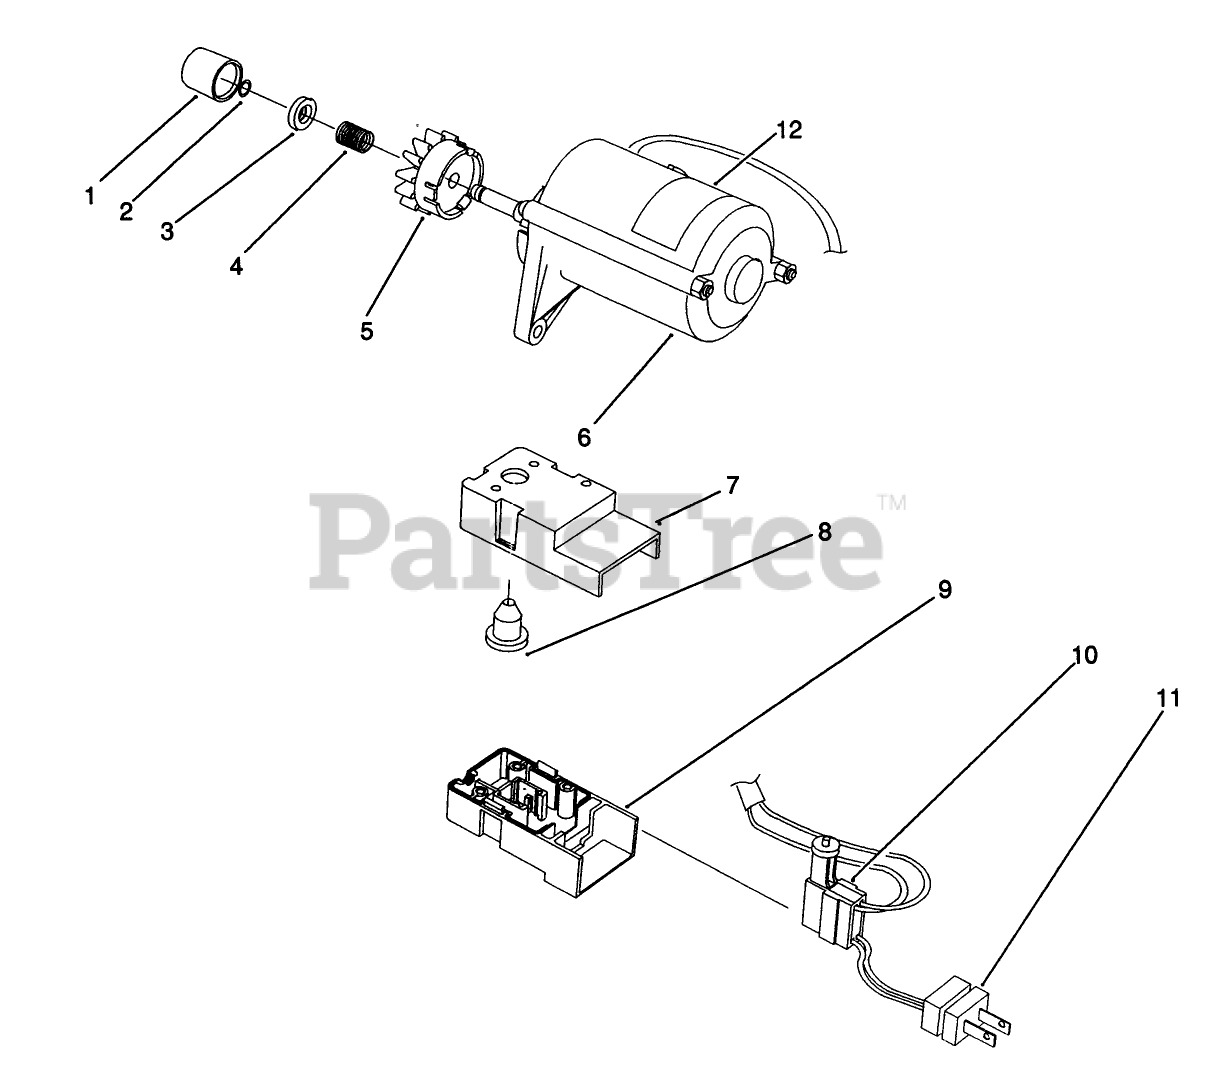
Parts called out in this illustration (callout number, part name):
1	CAP-PINION
2	RING-LOCK
3	PINION STOP
4	SPRING
8	BOOT-SWITCH
10	SWITCH-STARTER
12	Decal-UL
